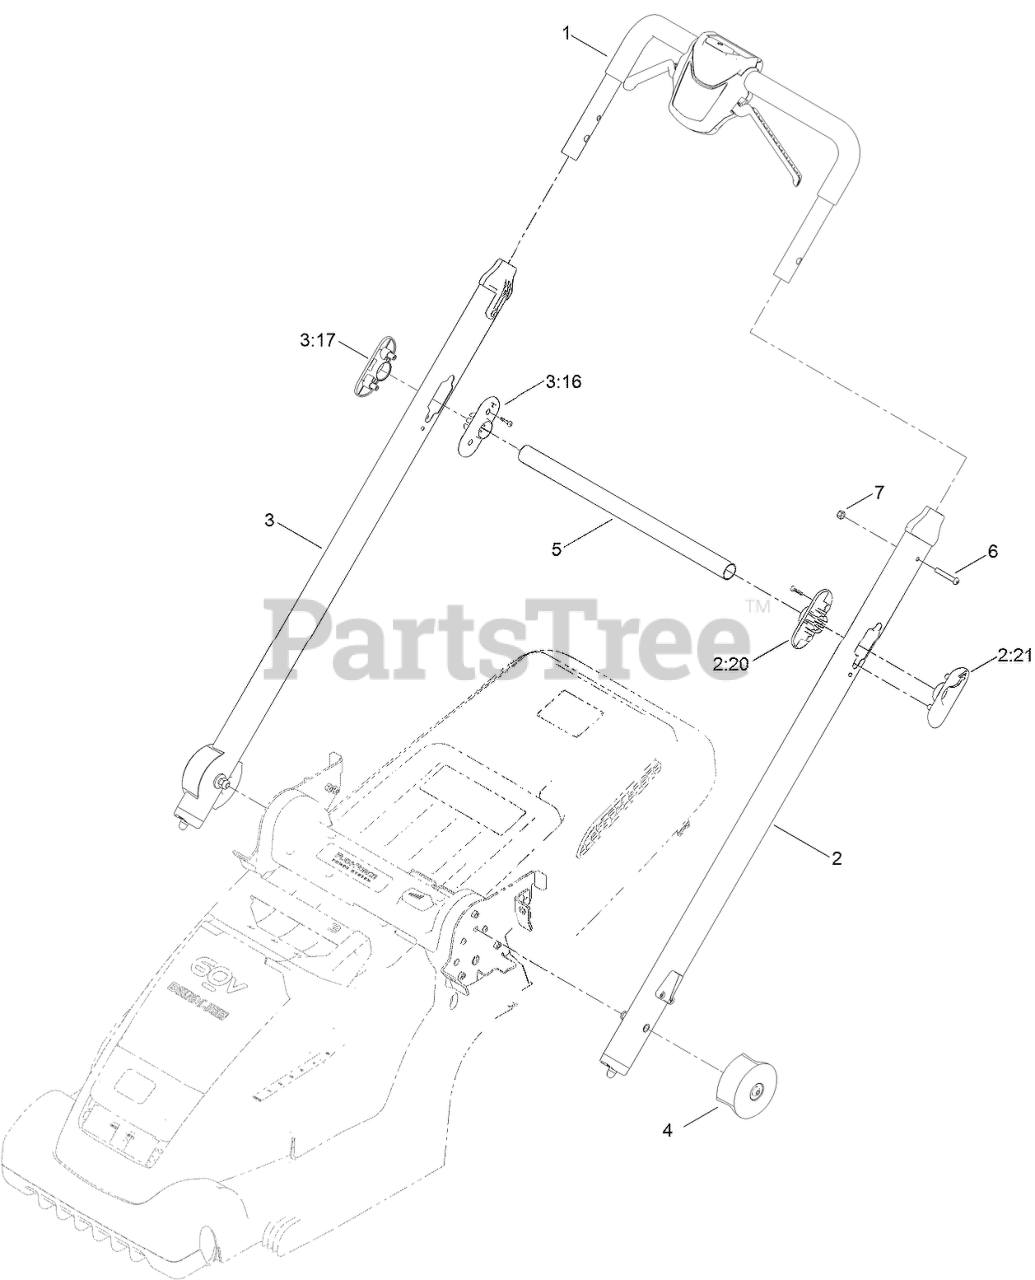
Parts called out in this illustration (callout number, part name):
1	CONTROL LEVER ASM, PUSH
2	HANDLEBAR ASM, LH
2:20	HANDLEBAR BRACE - INNER
2:21	HANDLEBAR BRACE, OUTER
3	HANDLEBAR ASM, RH
3:16	HANDLEBAR BRACE - INNER
3:17	HANDLEBAR BRACE, OUTER
4	HANDLEBAR END CAP
5	BRACE, HANDLEBAR RELEASE
6	BOLT, M6X40
7	NUT, M6, NYLOC
